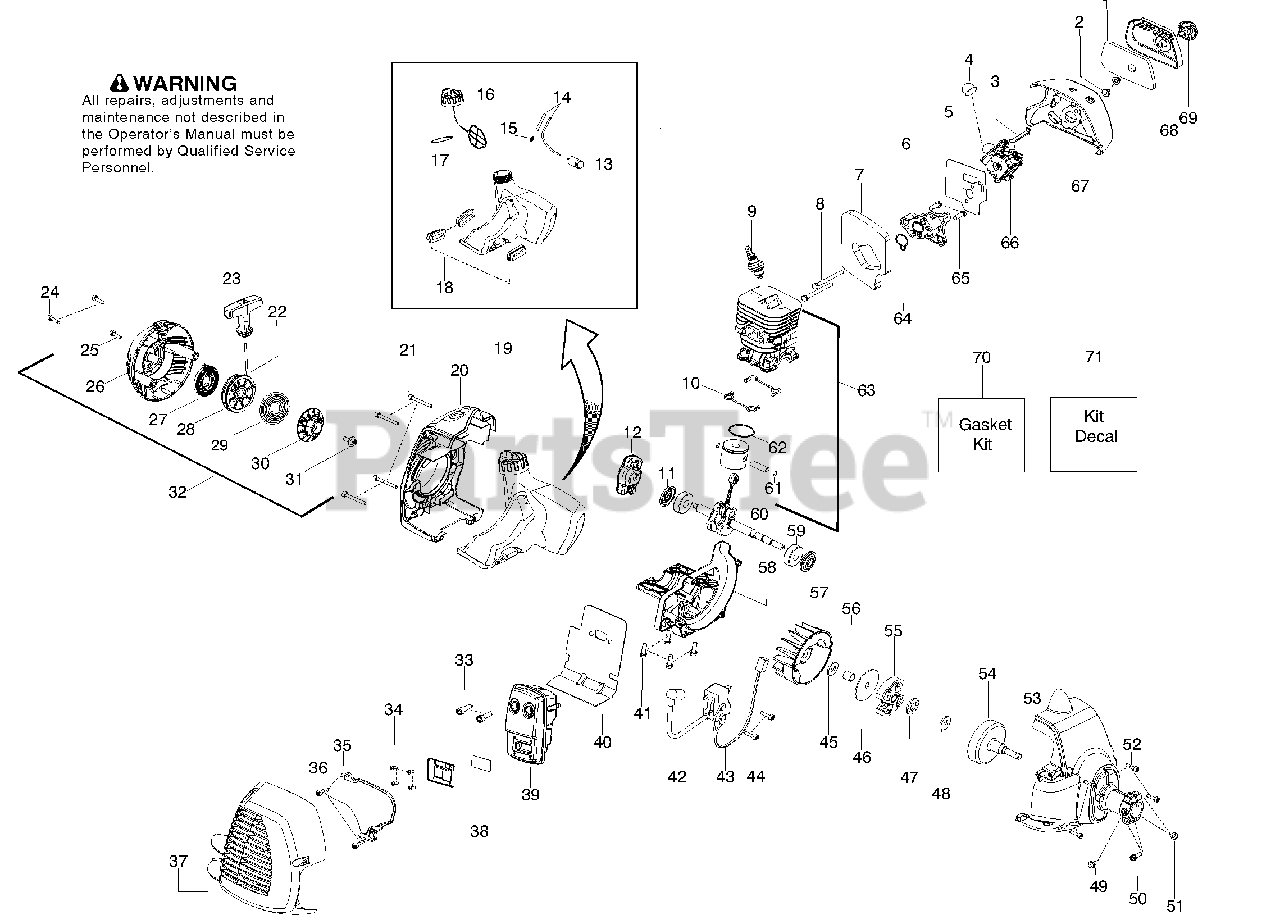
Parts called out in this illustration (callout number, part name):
2	Nut - Carb. Screw
3	Lever - Choke
4	Bulb - Purge
5	Kit - Carb. Gasket
6	Adaptor - Carb.
7	Foam - Gasket (kit)
9	Plug - Spark (RCJ-8Y)
10	Seal - Cylinder (kit)
11	Seal - Crankshaft (kit)
12	Assy - Starter Pawl
13	Assy - Fuel Filter
14	Kit - Fuel Line
15	Fitting - Fuel line
16	Assy - Cap w/ret.
17	O-ring - Fuel Cap (kit)
18	Isolator - Fuel Tank
19	Kit - Fuel Tank Assy.
20	Shroud - Rear (KIT)
22	Kit - Rope
23	Handle - Starter
26	Hsg. - Starter (KIT)
27	Kit - Spring
28	Kit - Starter Pulley
29	Spring - Driver
30	Pulley - Driver
32	Assy - Starter Hsg.
33	Bolt - Muffler
34	Screw
35	Shield - Heat
37	Kit - Muffler Guard
38	Kit - Spark
39	Kit - Muffler
40	Gasket - Paper Met.(kit)
43	Assy - Leadwire
46	Washer - Clutch
47	Bearing - Thrust
48	Washer - Thrust
49	Screw
50	Screw
53	Assy - Fan Housing
54	Assy - Clutch Drum
55	Assy - Clutch
58	Crankcase - Cast
60	Assy - Crankshaft
61	Retainer - Piston Pin
62	Ring - Piston
63	Kit - Piston/Cyl.
64	Seal - adaptor (kit)
66	Kit - Carb.
67	Airbox
68	Cover - Air Box
69	Assy - Knob
70	Kit - Gasket
71	Kit - Decal
